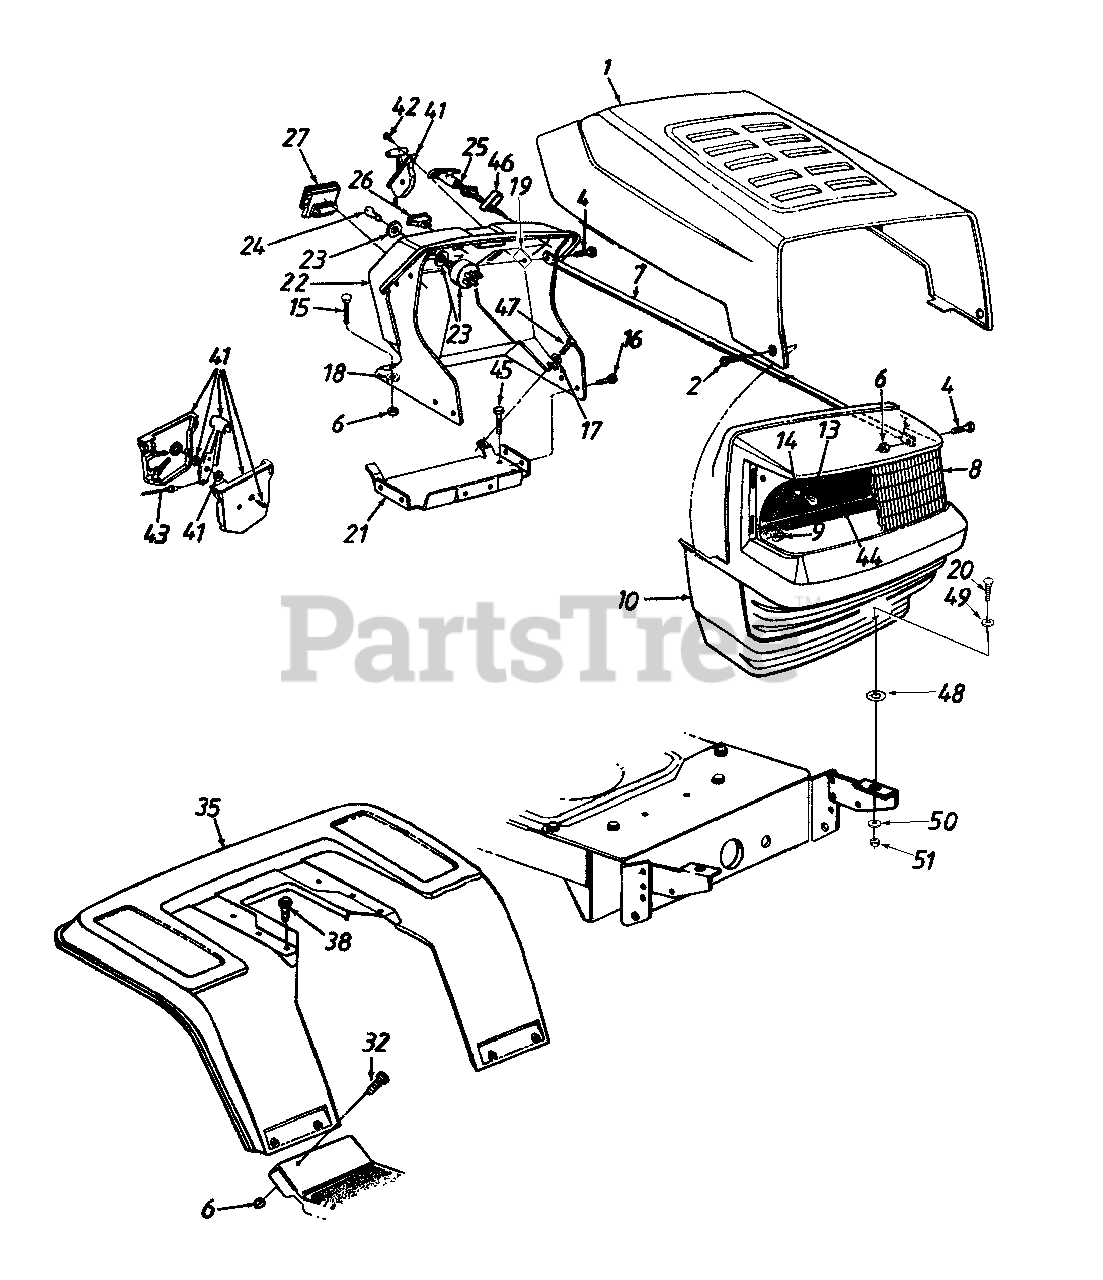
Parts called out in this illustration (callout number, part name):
4	Pan Hd. Scr.1/4-20 x .75" Lg.
6	Hex Sems Nut 1/4-20 Thd.
8	Headlight Lens w/o Logo
9	Flange Lock Nut 1/4-20 Thd.
10	Grille
13	Lamp
14	Socket
15	Carriage Bolt 1/4-20 x .75" Lg.
16	Hex Wash. Hd. TT-Tap Scr. 1/4-20 x .5"
17	Flat Washer .281" I.D. x .73" O.D.
18	Bolt Retainer 1/4" I.D.
19	Speed Nut 1/4-20 Thd.
20	Hex Bolt 5/16-18 x .75" Lg. (Gr.5)
23	Ignition Switch
24	Ignition Key
25	Choke Control 23" Lg.
26	Light Switch
27	Ammeter
32	Truss Mach. Scr. 1/4-20 x .5" Lg.
41	Throttle Box Assembly
42	Truss Mach. AB-Tap Scr. #10 x .5" Lg.
43	Throttle Control Wire 18.5" Lg.
44	Grille Reflector Label
45	Hex Wash. Hd. B-Tap Scr. 5/16-18 x .5"
46	Choke Retainer
47	Hex TT-Tap Scr. 1/4-20 x .75" Lg.
48	U-Nut 5/16-18 Thd.
49	Flat Washer .34" I.D. x 1" O.D.
50	Lock Washer 5/16" I.D.
51	Hex Nut 5/16-18 Thd. (Gr.5)
